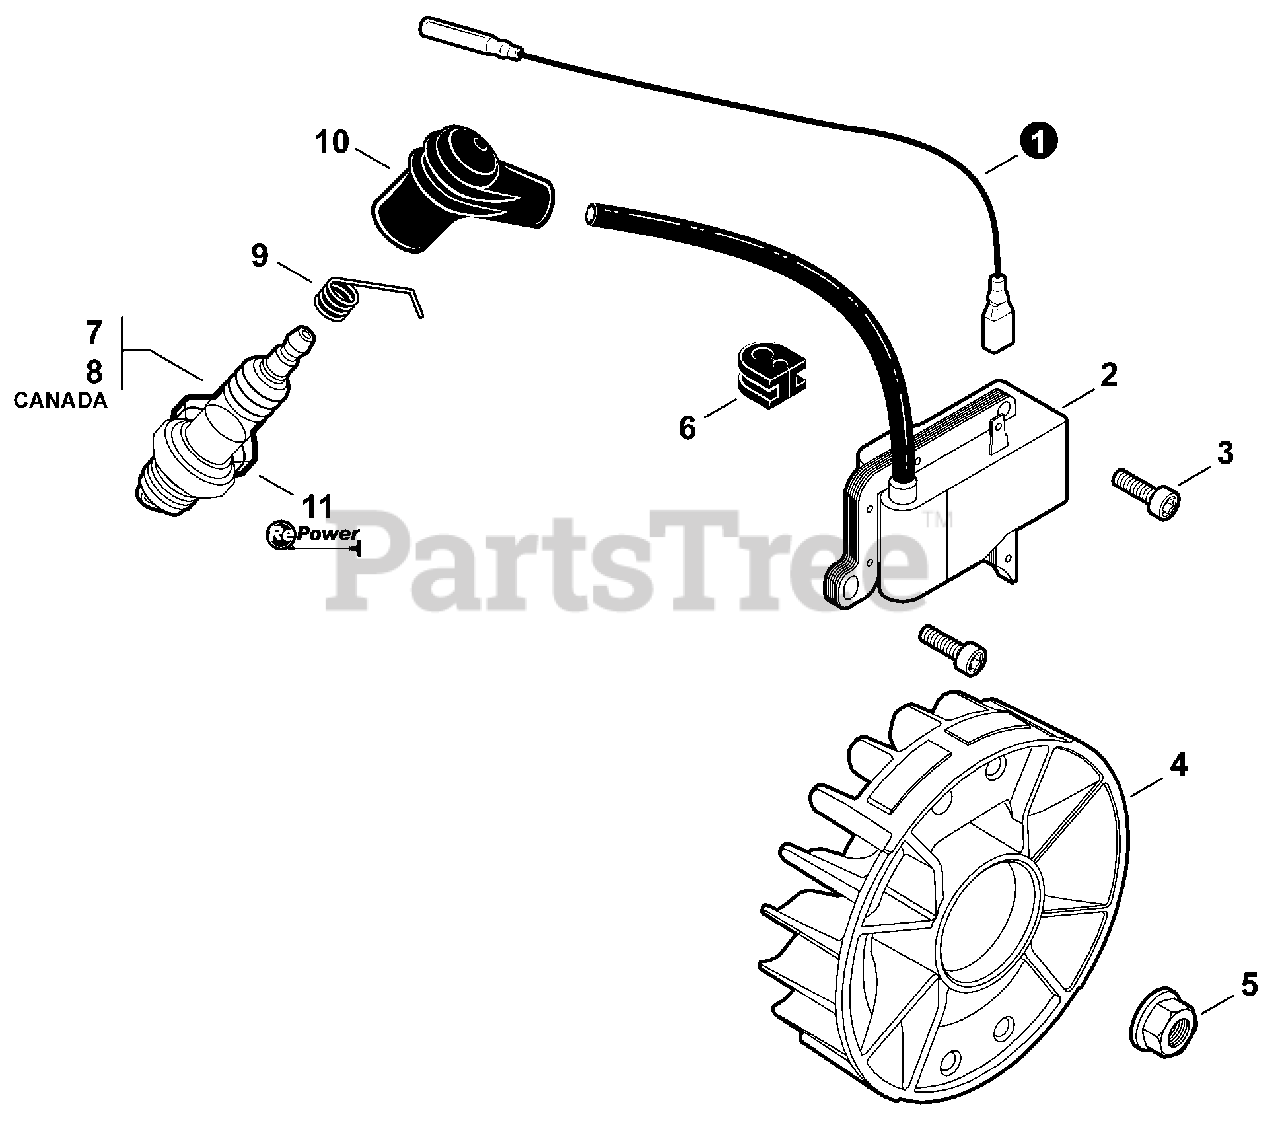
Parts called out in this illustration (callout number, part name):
1	LEAD L= 470
2	COIL, IGNITION
3	BOLT, TORX 5×20
4	FLYWHEEL
5	NUT, FLANGE 10×1.25
7	SPARK PLUG - BPM8Y
8	SPARK PLUG - BPMR8Y
9	TERMINAL, SPARK PLUG
10	CAP, SPARK PLUG
11	TUNE-UP KIT - REPOWER
